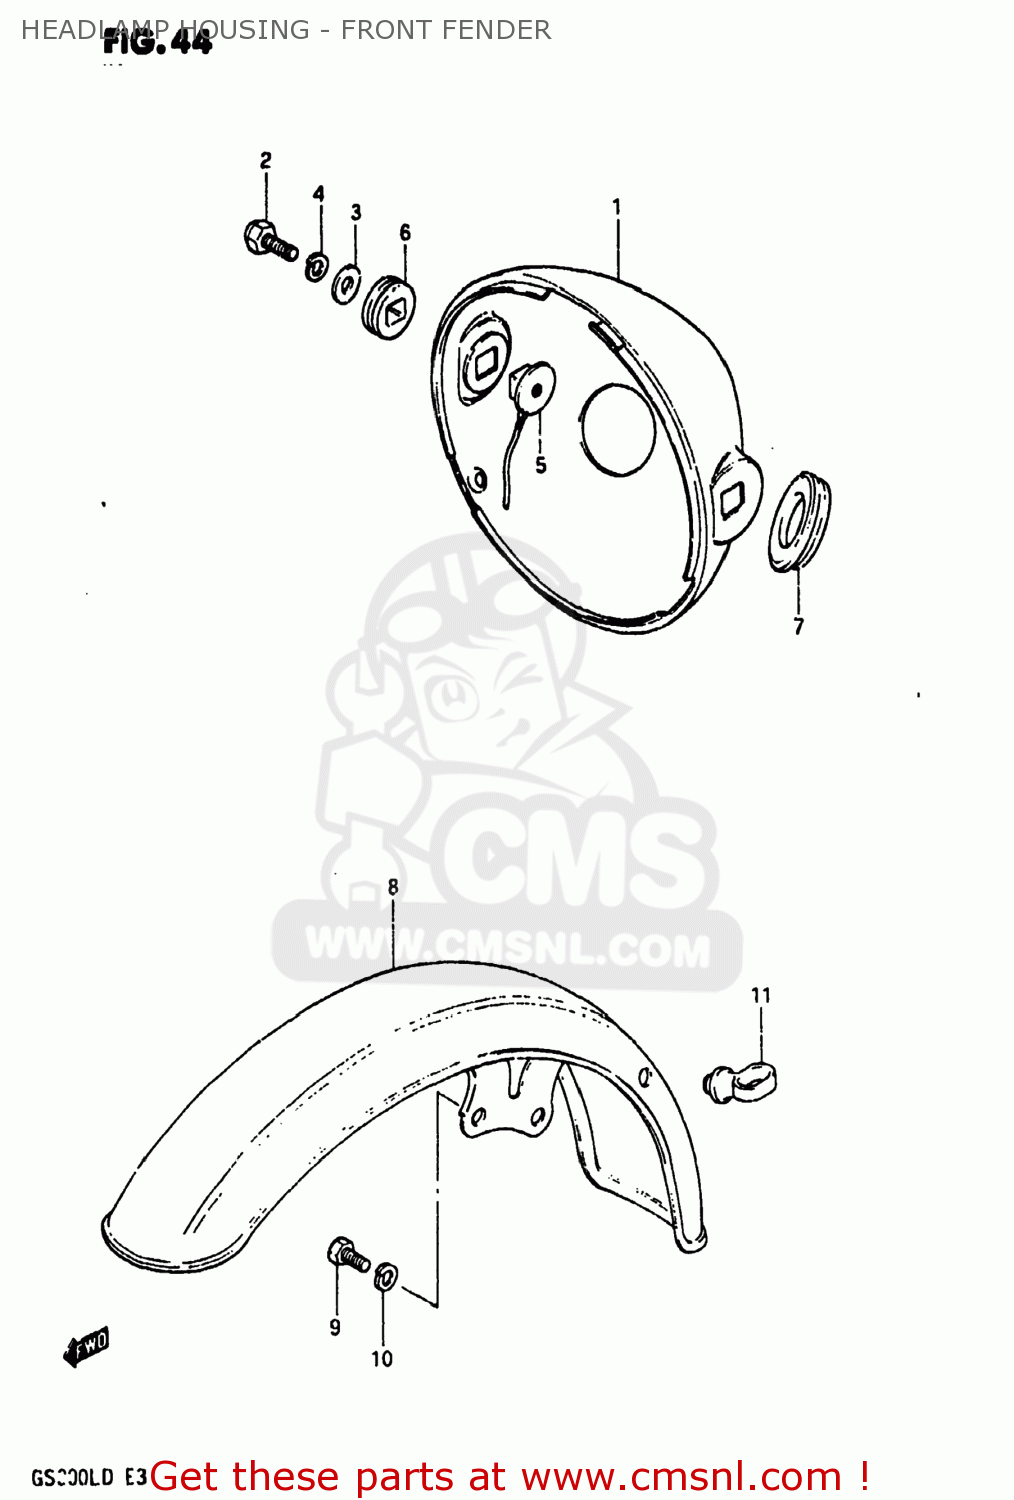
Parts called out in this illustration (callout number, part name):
1	HOUSING,HEADLAMP
2	BOLT
3	WASHER
4	LOCK WASHER
5	SPACER,HEADLAMP HOUSING
6	CUSHION,HEADLAMP HOUSING
7	GROMMET,HEADLAMP HOUSING
8	FENDER,FRONT
9	BOLT
10	LOCK WASHER
11	GUIDE,CABLE
